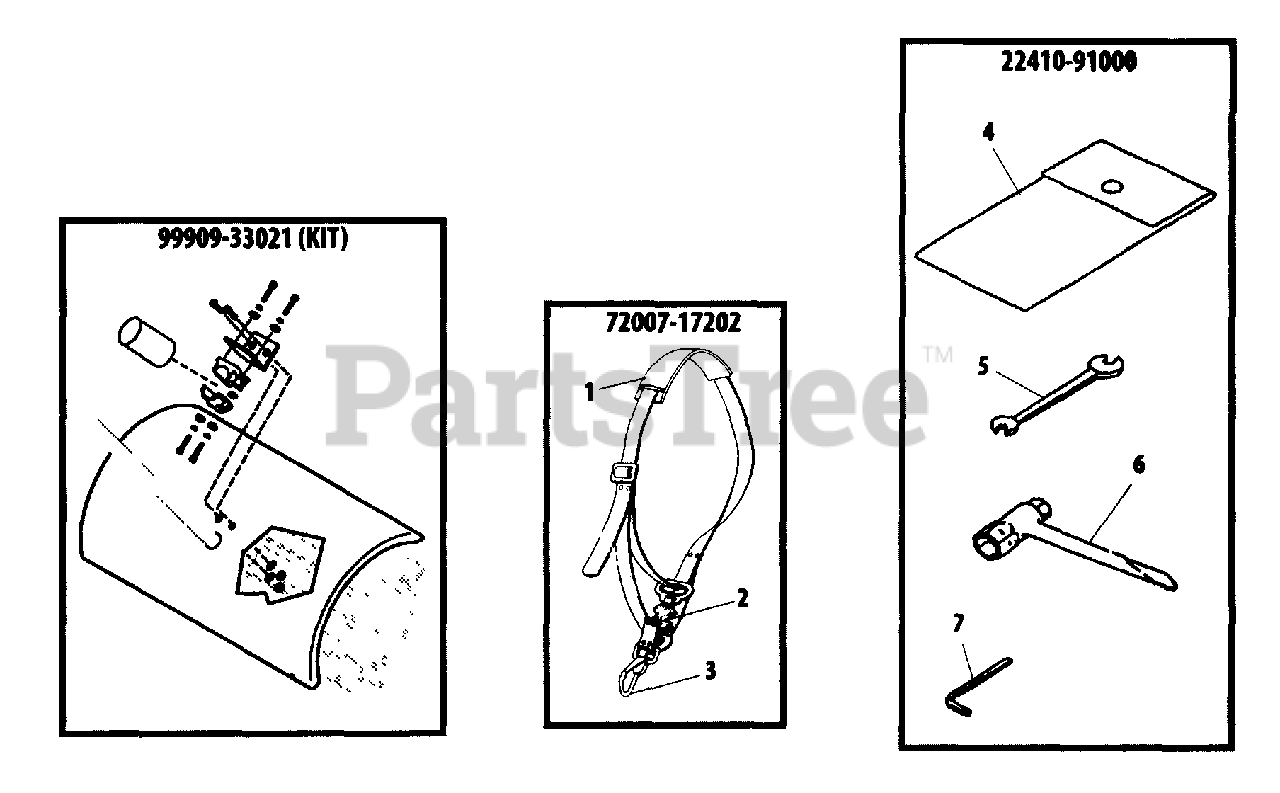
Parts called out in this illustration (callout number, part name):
1	PAD
2	CUSHION, HARNESS
3	HOOK
4	BAG, TOOL
5	SPANNER - 8X10mm
6	T-WRENCH - 13X19mm
7	HEX KEY - 4mm
